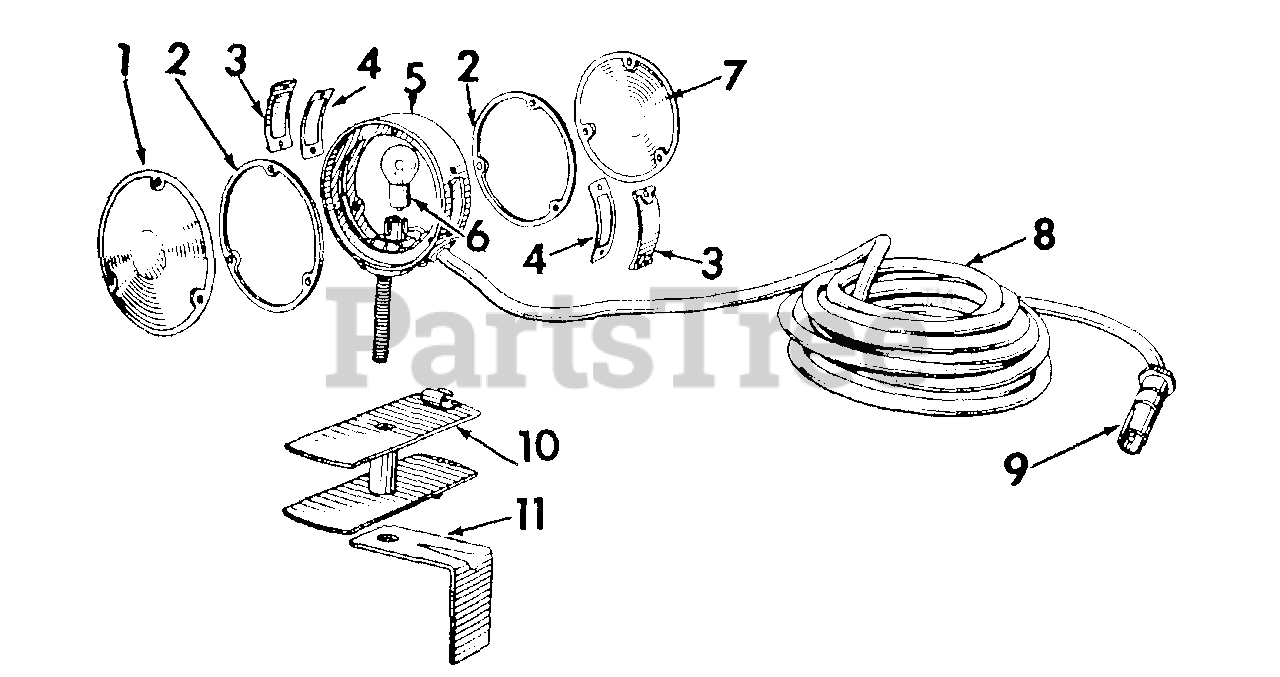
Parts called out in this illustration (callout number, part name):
1	LENS, SAFETY LIGHT -RED-
2	GASKET, SAFETY LIGHT LENS
3	LENS, SAFETY LIGHT OUTLOOK
4	GASKET, SAFETY LIGHT OUTLOOK LENS
5	BODY, SAFETY LIGHT
6	LAMP, NO 1129 - 6 VOLT
7	LENS, SAFETY LIGHT -AMBER-
8	CABLE, 22 FOOT SAFETY LIGHT
9	PLUG. BREAK-AWAY CONNECTOR SOCKET
10	SPOOL, SAFETY LIGHT
11	BRACKET, SAFETY LIGHT MOUNTING
